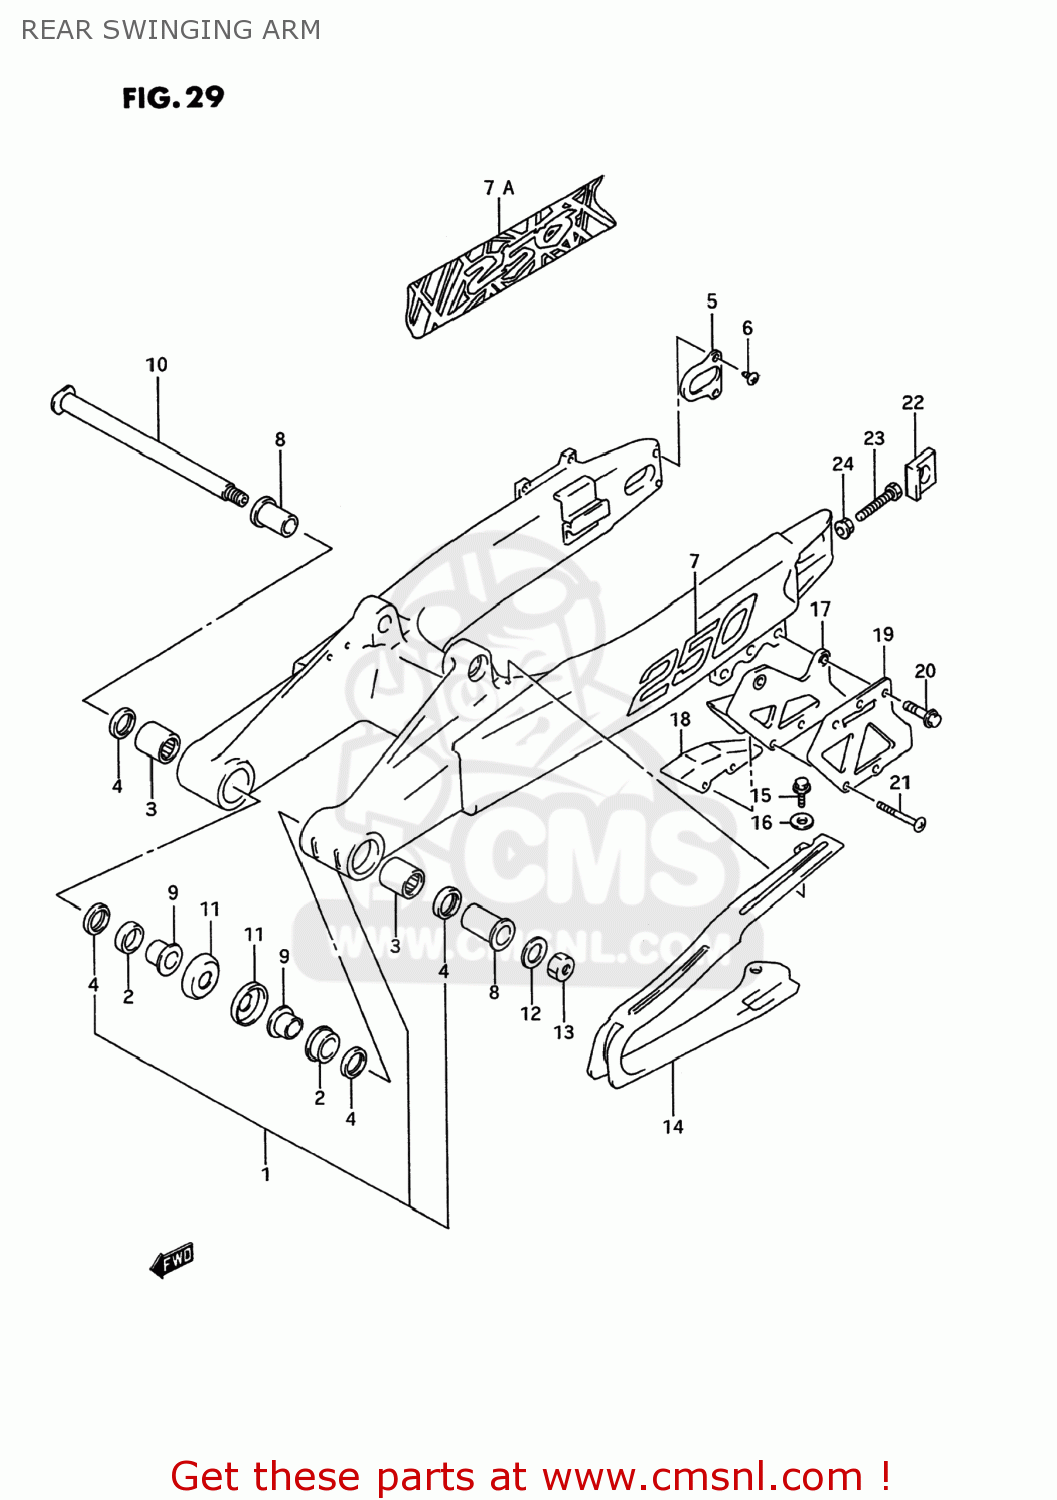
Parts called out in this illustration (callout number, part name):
1	SWING ARM ASSEMBLY,REAR
2	BUSHING,SWGARM PIVOT
3	BEARING(22X29X30)
4	SEAL,OIL(22X29X4)
5	PLATE,SWING ARM,REAR
6	SCREW(5X8)
7	EMBLEM,SWINGINGARM
7A	EMBLEM,SWING ARM
8	SPACER,RR SWGARM PIVOT
9	SPACER,SWGARM PIVOT INNER
10	SHAFT,RR SWINGINGARM PIVOT
11	COVER,SWINGINGARM PIVOT
12	WASHER
13	NUT
14	BUFFER,CHAIN TOUCH DEFENSE
15	BOLT
16	WASHER
17	GUIDE,CHAIN
18	DEFENSE,CHAIN GUIDE
19	PLATE,CHAIN GUIDE OUTER
20	BOLT
21	SCREW(6X40)
22	WASHER,CHAIN ADJUSTER
23	BOLT(8X50)
24	NUT
